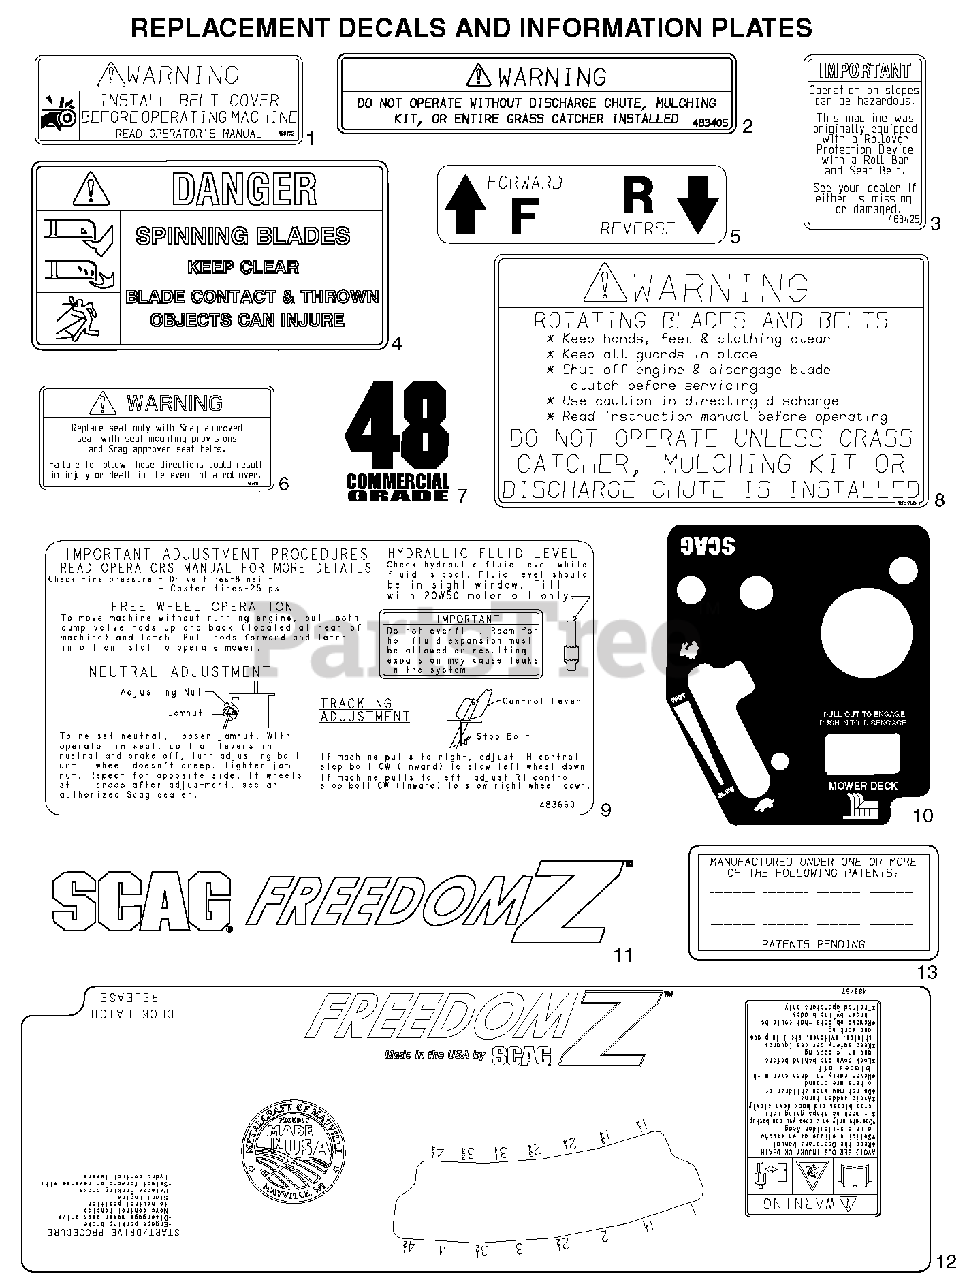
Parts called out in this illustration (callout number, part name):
1	Decal, Belt Cover
2	Decal, Warning
3	Decal, ROPS
4	Decal, Spinning Blades
5	Decal, Traction Control
6	Decal, Seat Replacement
7	Decal
8	Decal, Knives
9	Decal, Adjustment
10	Decal, Instrument Panel
11	Decal, Front
12	Decal, Cutting Height
13	Decal, Patent
